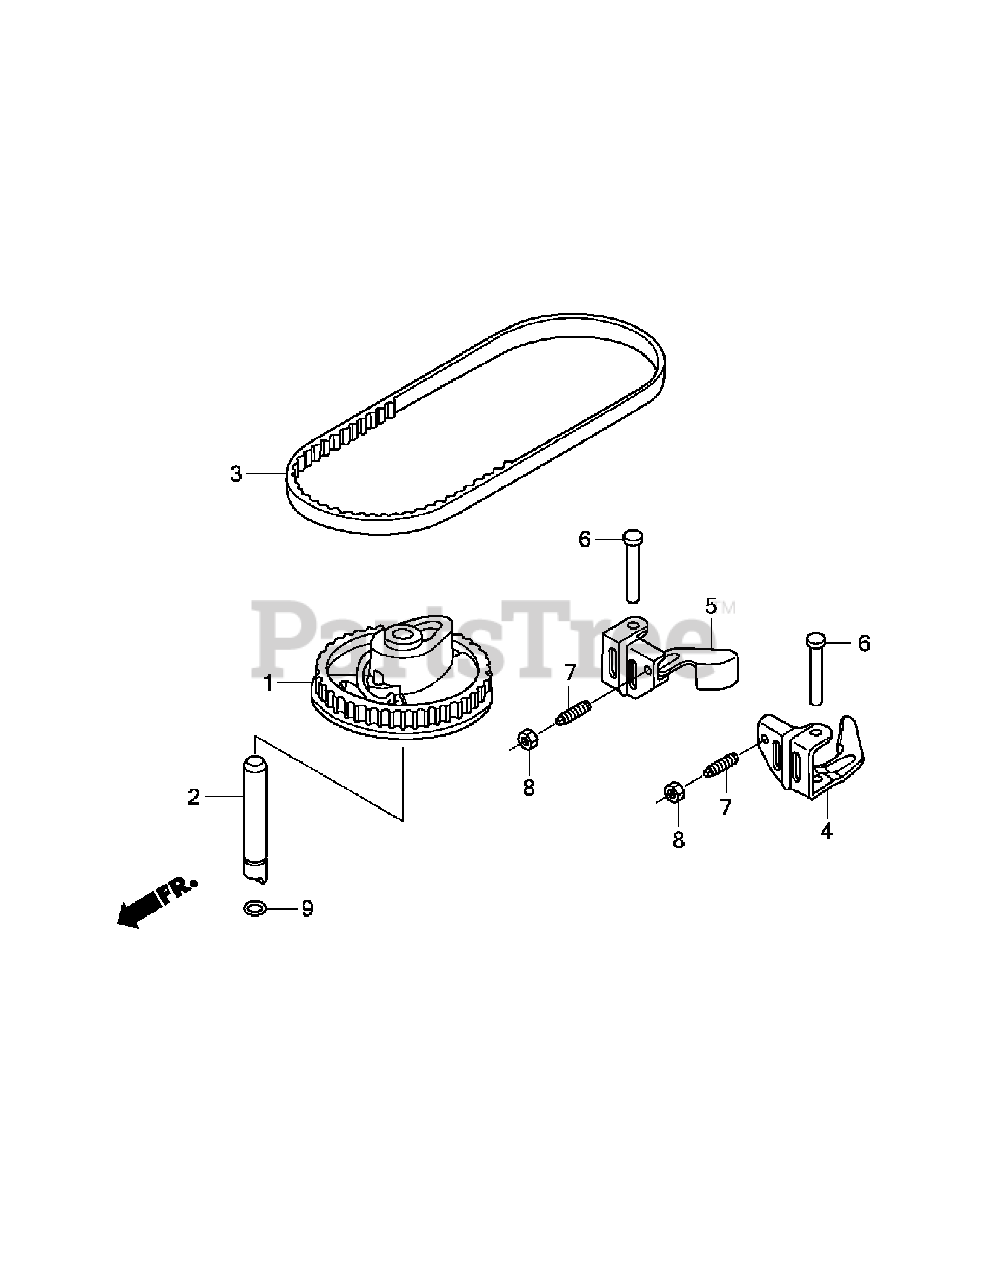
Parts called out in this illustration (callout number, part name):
1	Camshaft Pulley
2	Cam Pulley Shaft
3	Timing Belt
4	Intake Rocker Arm
5	Exhaust Rocker Arm
6	Rocker Arm Shaft
7	Tappet Adjusting Screw
8	Tappet Adjusting Nut
9	O-Ring,6.8x1.9
